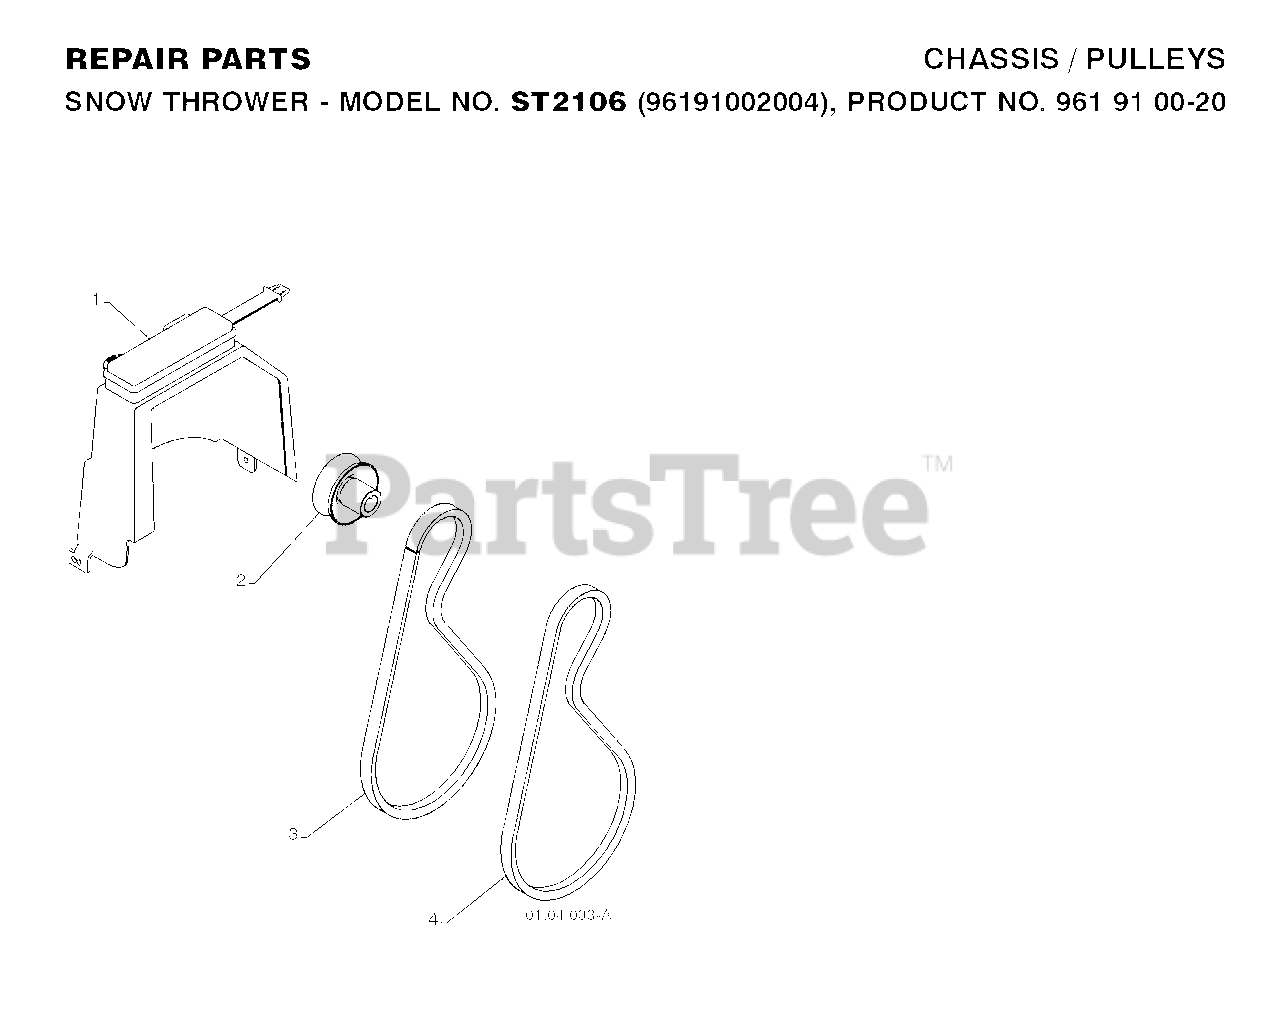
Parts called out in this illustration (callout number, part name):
1	COVER.ASM.BELT/STORAGE
2	PULLEY, ENGINE IMPELLER DRIVE
3	V-BELT.TRACTION
4	BELT.V.IMPELLER
